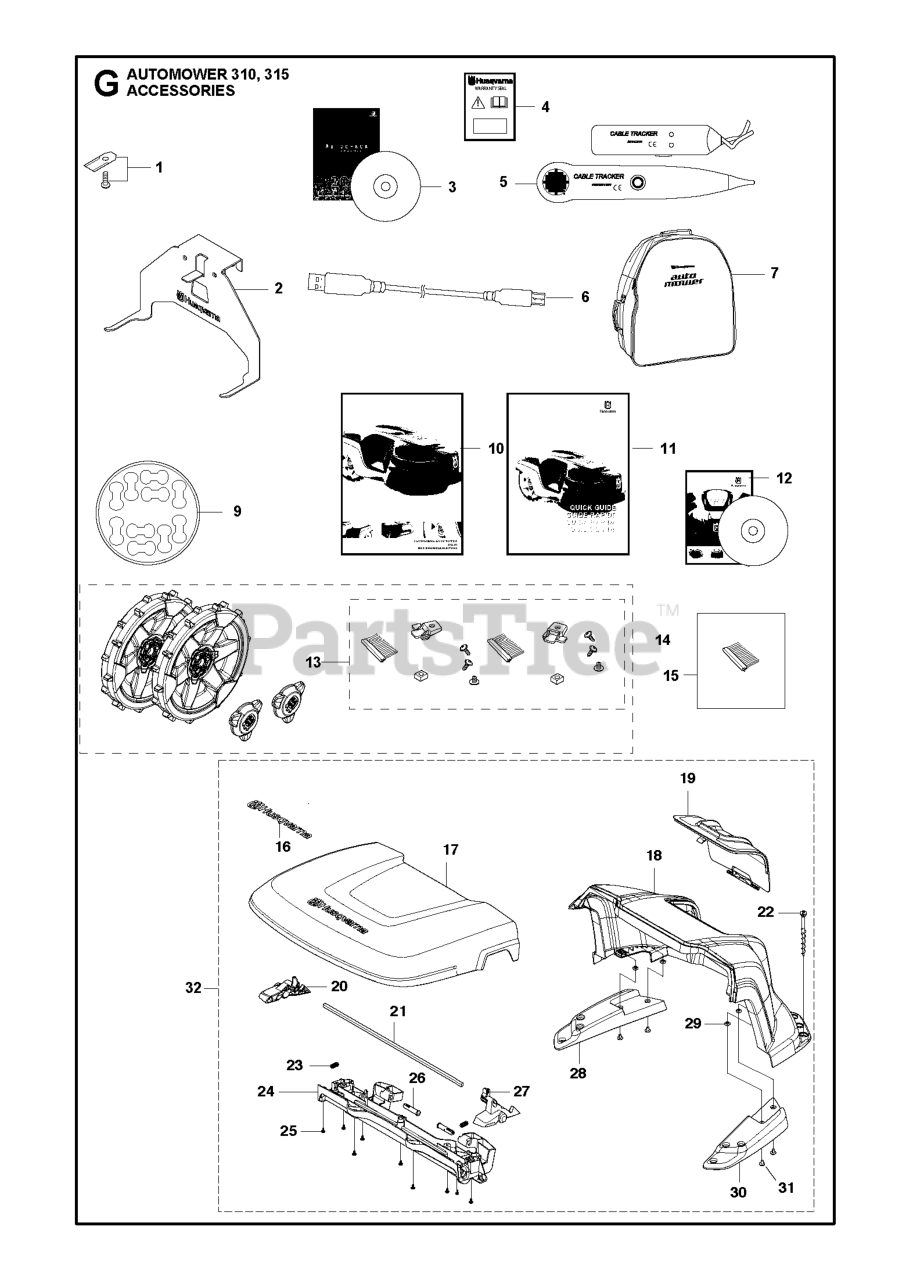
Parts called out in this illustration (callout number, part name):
1	BLADE SET 300 PCS. CARBON STEE
1	BLADE KIT HUSQVARNA 9 PCS 50HR
1	BLADE SET 45 PCS
2	315 WALL HANGER
3	DVD AUTOCHECK EXP SERVICE
4	LABEL WARRANTY SEAL KIT 10 PK
4	LABEL WARRANTY SEAL DEALER
5	TEST EQUIPMENT
6	CABLE WHITE ALT GREY
9	STICKER CABLE MARKERS KIT 10PC
12	CD DVD MANUALS 305, 308, 310,
13	WHEEL BRUSH KIT 315
14	WHEEL KIT AM310/315. HEAVY REA
15	BRUSH KIT - ONLY BRUSHES 6 PCS
16	DECAL.HUSQVARNA.210MM
17	COVER LID 315
18	COVER BASE P15
20	HANDLE RELEASE LEFT
22	SCREW KIT CS
23	SPRING SPRING CAP
25	SCREW 14MM
27	HANDLE RELEASE RIGHT
28	SUPPORT BASE LEFT
30	SUPPORT BASE RIGHT
31	SCREW IHPANM M6X25 4.6 ZP-BC
32	HOUSE KIT FOR 315
